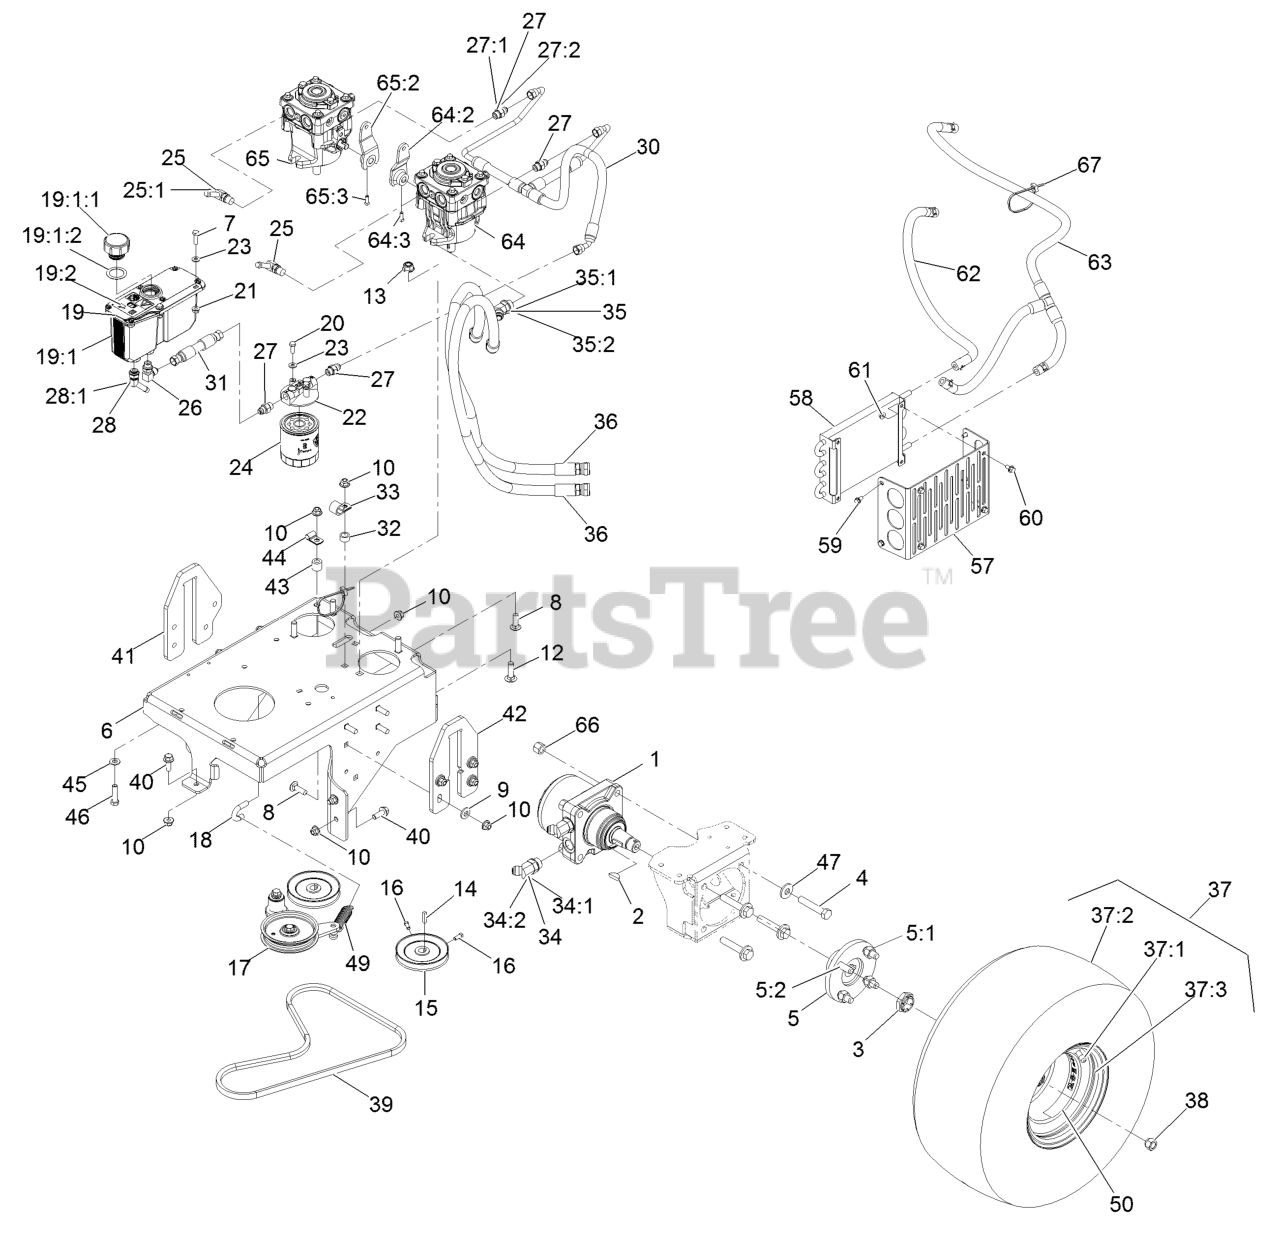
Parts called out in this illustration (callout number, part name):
1	MOTOR-WHEEL
2	KEY-WOODRUFF
3	LOCKNUT
4	SCREW-HH
5	WHEEL HUB / STUD ASM
5:1	HUB-WHEEL
5:2	STUD-TYPE, DRIVE
6	WELDMENT, FRAME
7	SCREW-HH
8	BOLT-CARR
9	WASHER-BELLEVILLE
10	NUT-HF, NI
12	SCREW-HH
13	NUT-HF, NI
15	PULLEY-PUMP
16	SCREW-SET
17	PUMP IDLER ASM
18	ANCHOR, SPRING
19	RESERVOIR ASM
19:1	Cap-Reservoir, HYD
19:1:1	Cap-Reservoir, HYD
19:1:2	GASKET-CAP
19:2	DECAL-WARNING
20	SCREW-HH
21	NUT-HHF
22	HEAD-FILTER
23	WASHER-FLAT
24	FILTER-25 MICRON, BI-DIRE
25	FITTING-ELBOW, 90
25:1	O-RING
26	FITTING-ELBOW, 90 DEG
27	FITTING-STRAIGHT
28	FITTING-BARBED, 45 DEG
28:1	O-RING
30	HOSE ASSEMBLY - CHARGE
31	HYD HOSE ASM
32	SPACER-WHEEL
33	CLIP-LOOM
34	FITTING-HYD, 45 DEG
35	FITTING-HYD, 45 DEG
36	HYD HOSE ASM
37	WHEEL/TIRE ASM
37:1	RIM-8 INCH
37:3	Stem-Valve
38	NUT-LUG
39	BELT-V, LOWER PTO
40	SCREW-HHF 3/8-16 X 1
41	PLATE-LIFT, RH
42	PLATE, LIFT LH
44	CLIP-TUBE
45	WASHER-FLAT
46	SCREW-HH
47	WASHER-SPRING
49	SPRING-EXTENSION
50	DECAL-TORQUE, WHEEL HUB LUG
57	BRACKET, COOLER MOUNTING
59	SCREW-HWH
60	SCREW-HHF
61	NUT-KEPS
62	HOSE, HYDRAULIC ASSY
63	HOSE ASM-HYD LP 3/8
64	PUMP W/ARM - LEFT
64:2	ARM-HYDRO
64:3	SCREW-SET
65	PUMP W/ARM -RIGHT
65:2	ARM-HYDRO
65:3	SCREW-SET
66	NUT-LOCK, NI
67	TIE-CABLE
